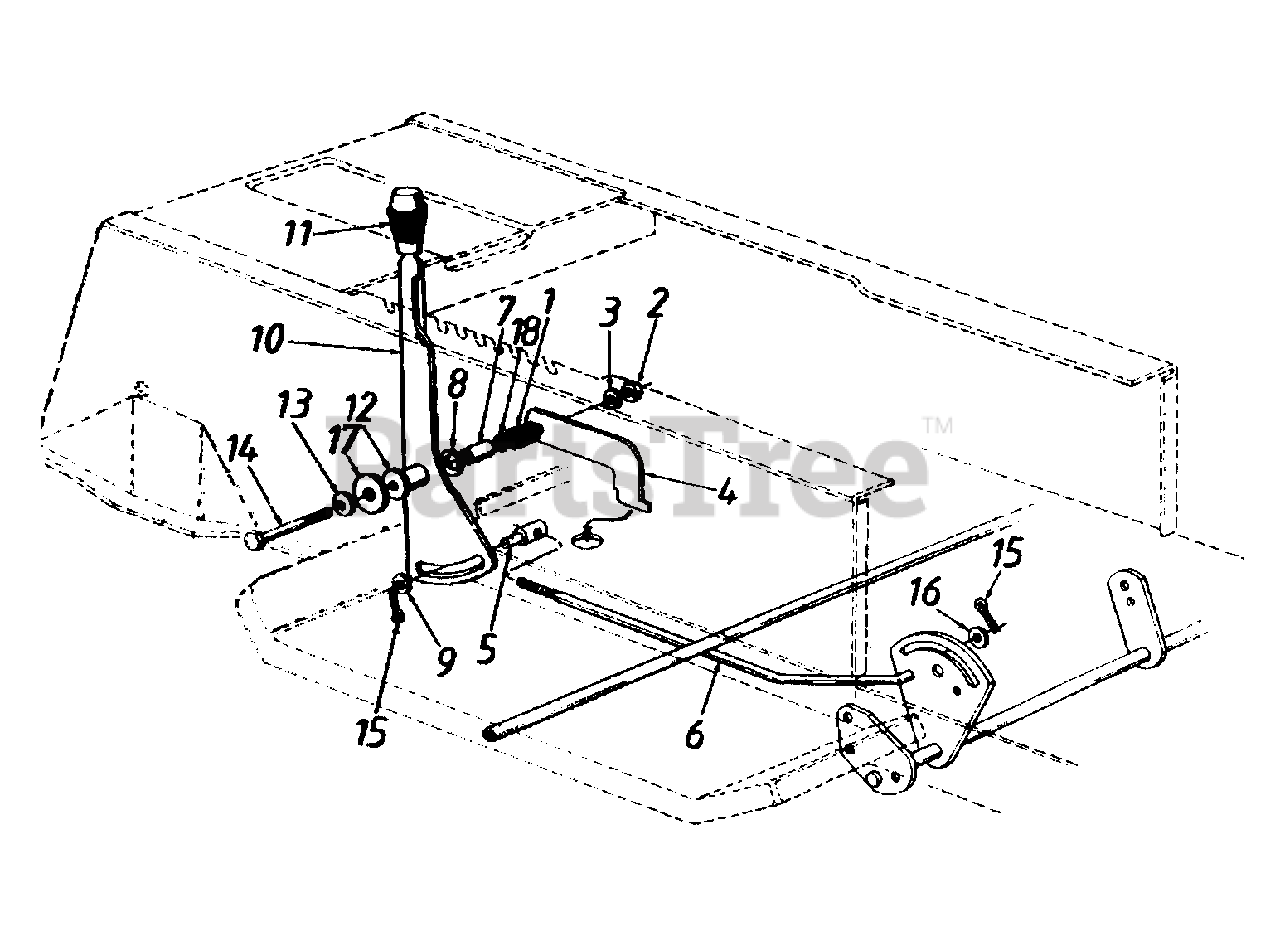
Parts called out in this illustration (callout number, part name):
1	Compression Spring
2	Hex Nut 5/16-18 Thd.
3	L-Wash. 5/16" I.D.
4	Shift Lever Support
5	Ferrule 3/8-24 Thd.
6	Speed Control Rod
7	Spacer 1.56" Lg.
8	Bell-Wash. .505" I.D. x 1"
9	Fl-Wash. .385" I.D. x .87"
10	Speed Selector Lever
11	Shift Knob
12	Spacer 1.46" Lg.
13	Fl-Wash. .345" I.D. x .88"
14	Hex Bolt 5/16-18 x 3.25" Lg.
15	Cotter Pin 3/32" Dia. x 1"
16	Fl-Wash. .469" I.D. x .88"
17	Fl-Wash. .34" I.D. x 2.25"
18	Speed Nut 5/16-18 Thd.
